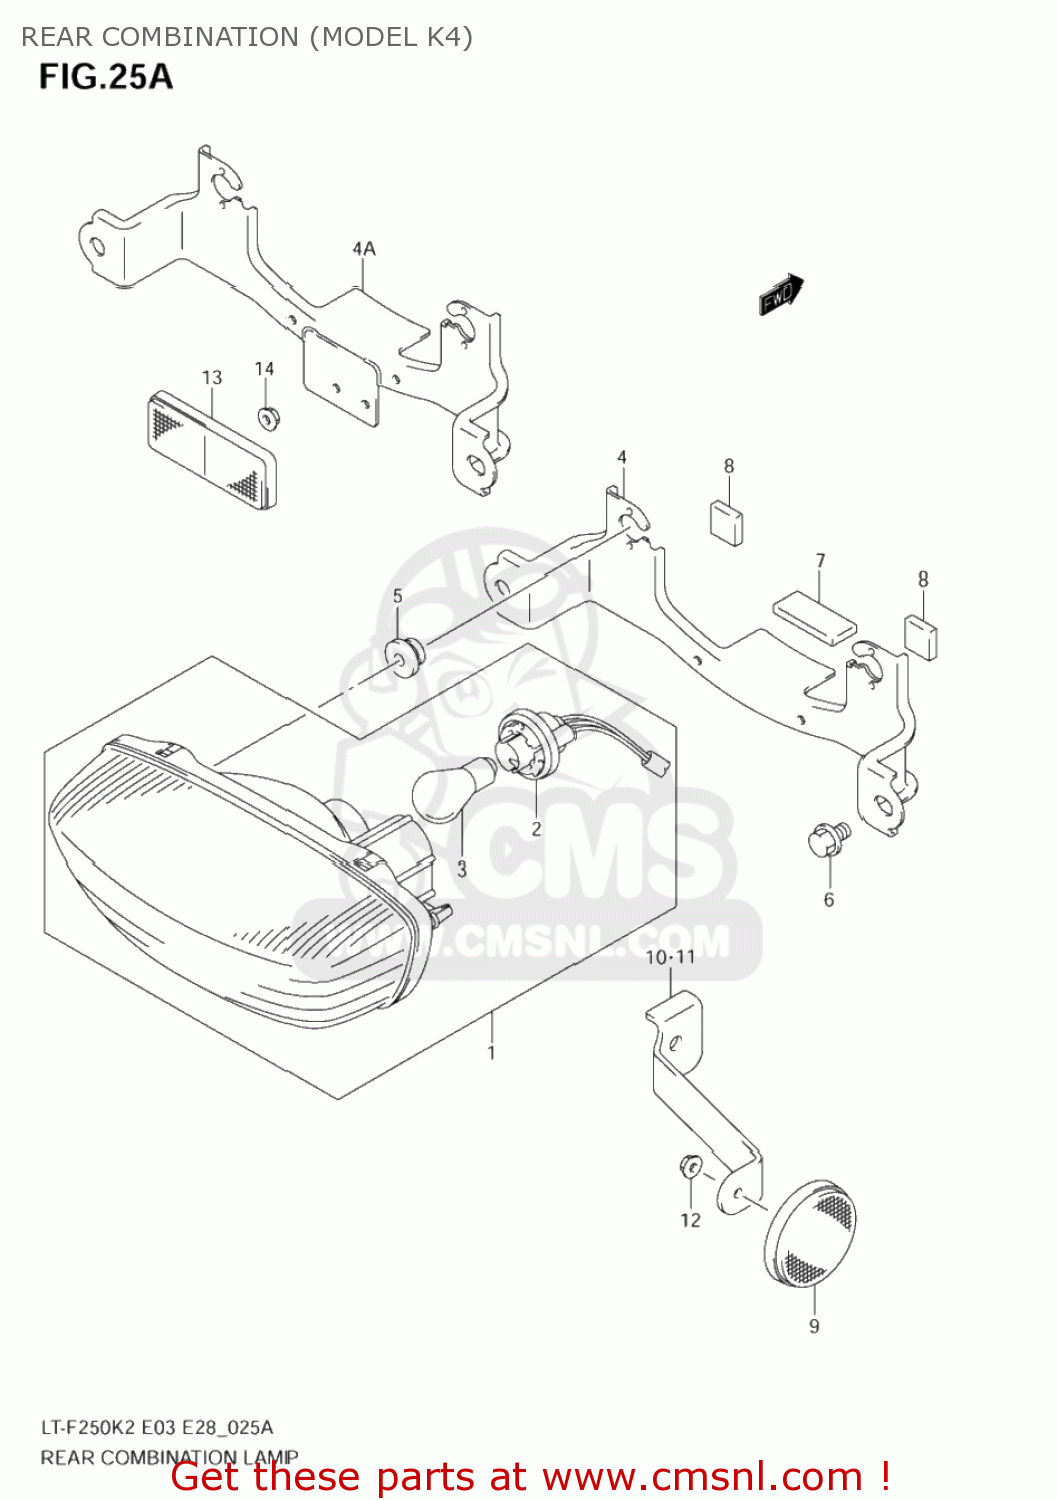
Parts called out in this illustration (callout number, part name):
1	LAMP ASSY,RR COMBINATION
2	SOCKET & CORD ASSY
3	BULB(12V21/5W)
4	BRACKET,RR COMBINATION LAMP
4A	BRACKET,RR LAMP
5	CUSHION
6	BOLT
7	CUSHION,RR LAMP(25X55X8)
8	CUSHION,RR LAMP(17X17X12)
9	REFLEX REFLECTOR,RR
10	BRACKET,RR SIDE RR,R
11	BRACKET,RR SIDE RR,L
12	NUT
13	REFLECTOR ASSEMBLY,REAR
14	NUT
